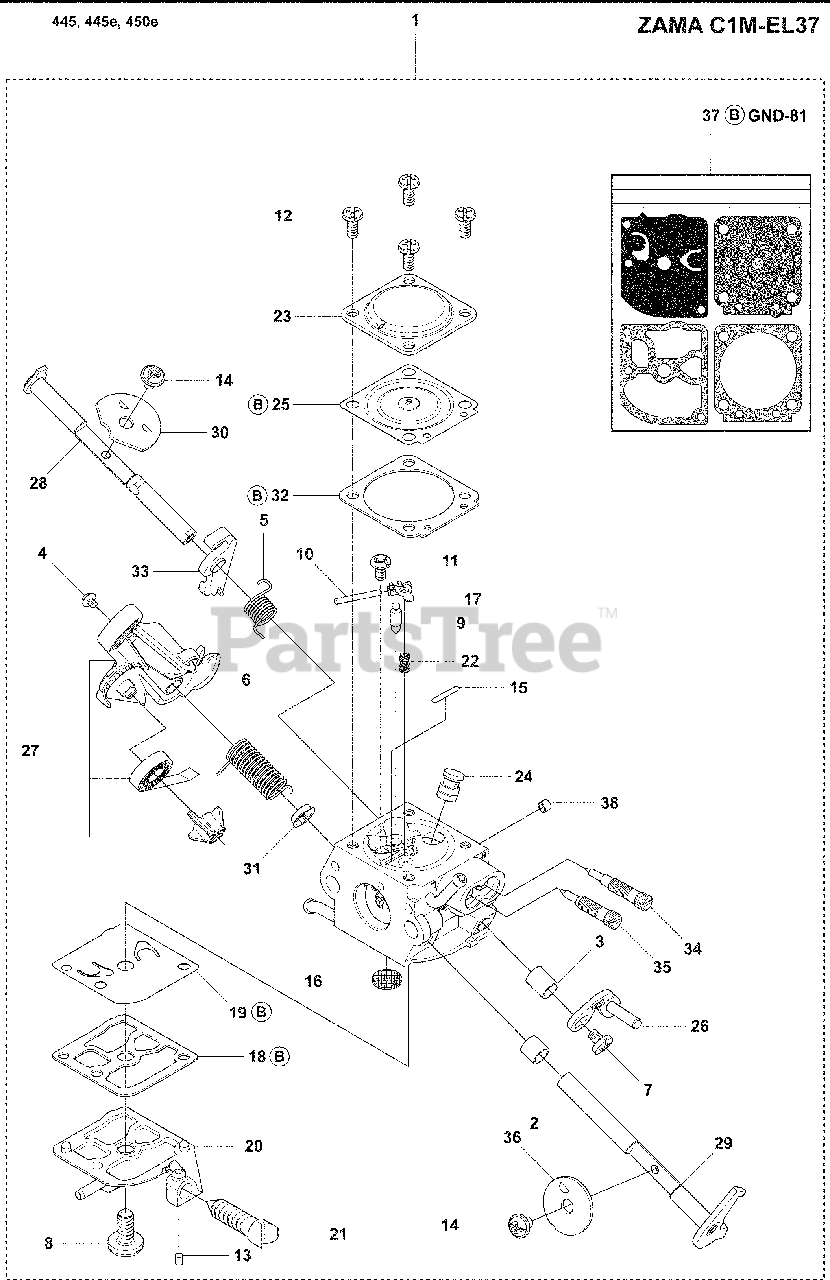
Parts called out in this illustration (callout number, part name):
1	Carburetor Kit with Hose
9	Inlet Needle
10	Pin
19	Pump Diaphragm
27	Throttle Lever
28	Shaft Assembly
29	Shaft Assembly
37	Gasket Kit
